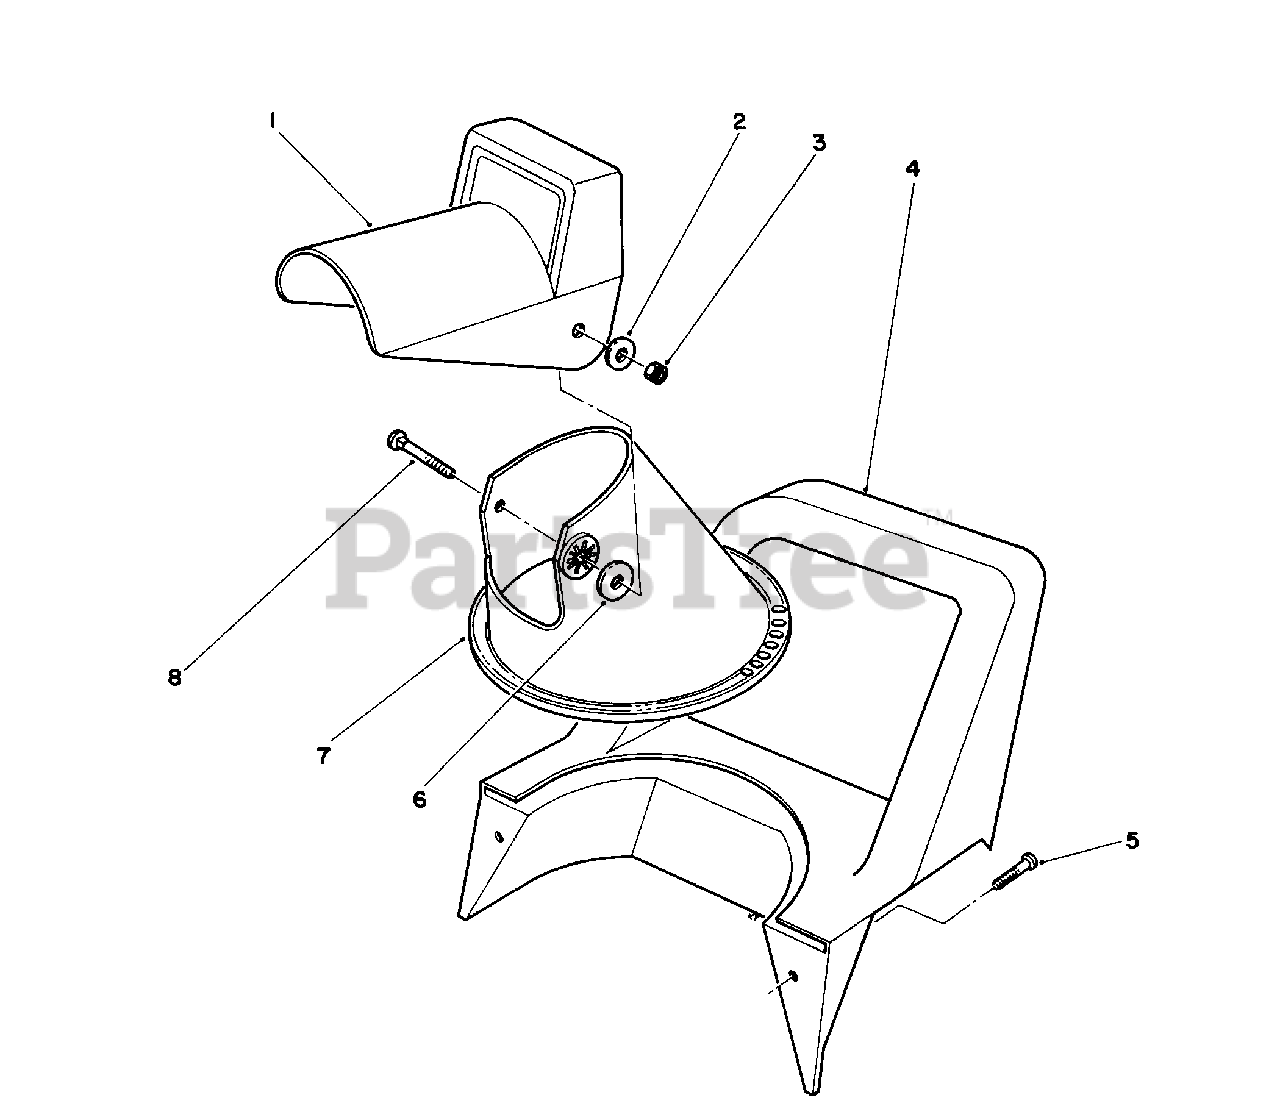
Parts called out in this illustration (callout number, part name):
1	Chute-Deflector
2	Washer-Flat
3	Nut-Lock
4	Handle-Middle
5	Screw-Pan Hd. Form.
6	Washer-Rubber
7	Chute-Lower
8	Bolt-Carriage
